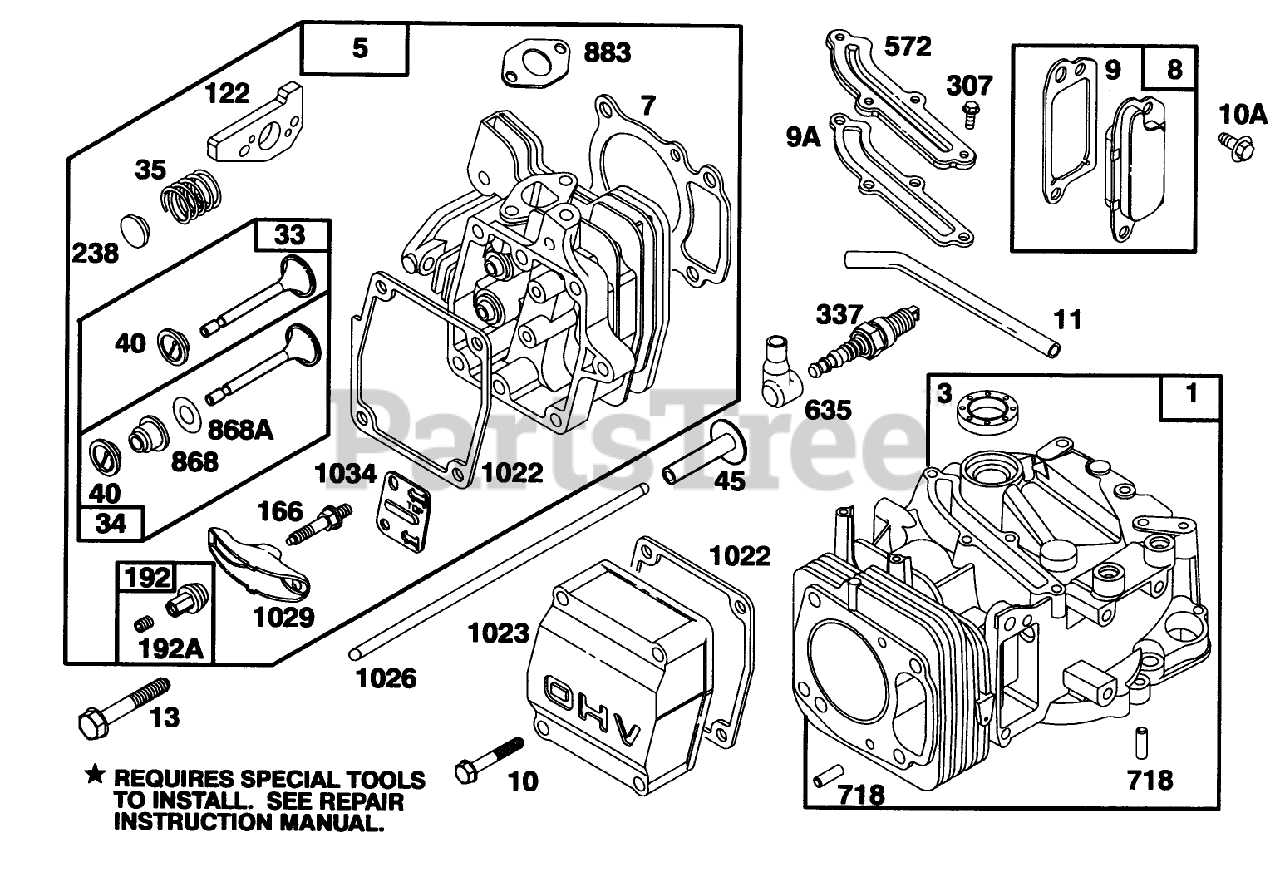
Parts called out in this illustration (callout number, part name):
3	SEAL - OIL
7	CYLINDER HEAD GASKET
9	BREATHER GASKET
9A	GASKET-BREATHER
12	ENGINE BASE GASKET
20	SEAL-OIL
104	FLOAT HINGE PIN
116	SEALING GASKET
116A	O RING SEAL
118	VALVE KIT - NEEDLE
121	CARBURATOR OVERHAUL KIT
122	ADAPTER ASSEMBLY
134	Valve-Inlet (Includes Seat)
137	FLOAT BOWL GASKET
163	AIR CLEANER GASKET
358	GASKET SET
524	O-RING
634	SEAL WASHER
842	O-RING
868	SealAssy-Valve
868A	Seal-Valve
883	EXHAUST GASKET
977	CARBURATOR GASKET SET
1022	ROCKER COVER GASKET
1039	VENT TUBE
1041	SEAL - FOAM
